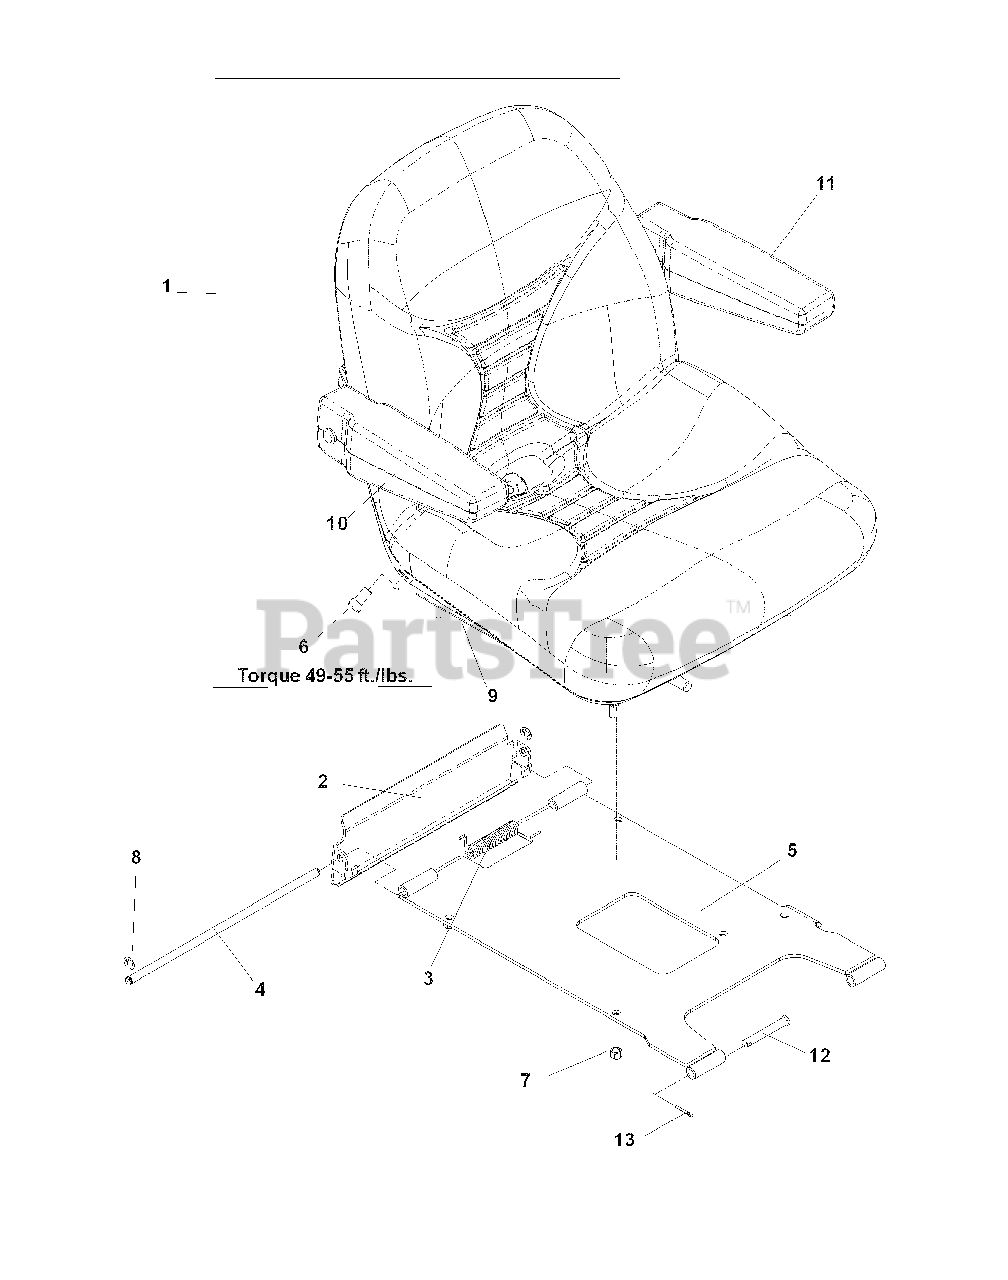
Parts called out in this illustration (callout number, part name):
1	SEAT, STANDARD
2	SEAT LATCH BRACKET
3	TORSION SPRING
4	SEAT LATCH ROD
5	SEAT MOUNT
6	HCS, 7/16-20 x 3/4
7	NUT, 5/16-18, NYLOC
8	RING-RETAINING
9	TRACK ADJUSTMENT KIT
10	ARM REST KIT, RIGHT
11	ARM REST KIT, LEFT
12	CLEVIS PIN
13	PIN, COTTER, 1/8 x 3/4
